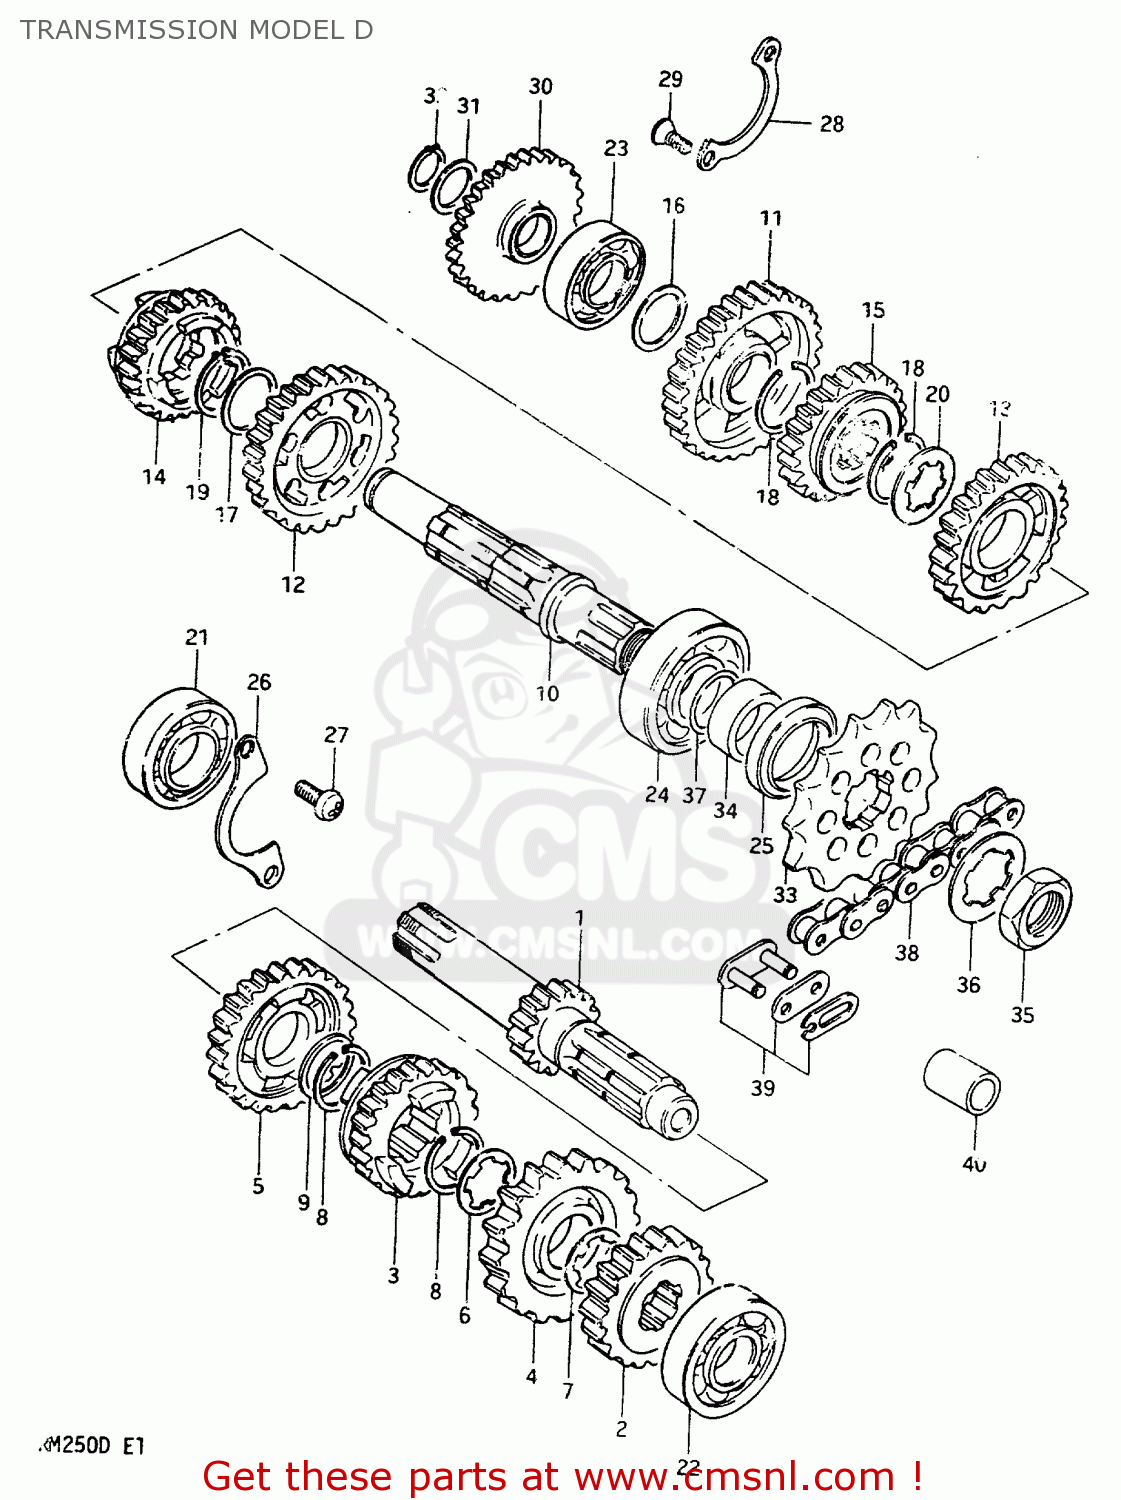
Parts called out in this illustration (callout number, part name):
1	SHAFT,COUNTER
2	GEAR,SECOND DRIVE
3	GEAR,THIRD DRIVE
4	GEAR,FOURTH DRIVE
5	GEAR,FIFTH DRIVE
6	WASHER,LOCK
7	WASHER,LOCK
8	CIRCLIP
9	SHIM(22X28X0.5)
10	SHAFT,DRIVE
11	GEAR,FIRST DRIVEN
12	GEAR,SECOND DRIVEN
13	GEAR,THIRD DRIVEN
14	GEAR,FOURTH DRIVEN
15	GEAR,FIFTH DRIVEN
16	WASHER
17	SHIM
18	CIRCLIP
19	CIRCLIP
20	WASHER,LOCK
21	BEARING(20X52X15)
22	BEARING(17X40X12)
23	BEARING(17X40X12)
24	BEARING
25	SEAL,OIL(32X42X6)
26	PLATE,COUNTERSHAFT BEARING
27	SCREW 6X12
28	PLATE,DRIVESHAFT BEARING
29	SCREW
30	GEAR,KICK STARTER IDLE
31	WASHER
32	CIRCLIP
33	SPROCKET,ENGINE
34	SPACER(22X32X9.5)
35	NUT
36	WASHER,LOCK
37	O RING(D:1.7,ID:22)
38	CHAIN ASSEMBLY,DRIVE
39	JOINT ASSEMBLY,CHAIN
40	SPACER(12X20X15.3)
